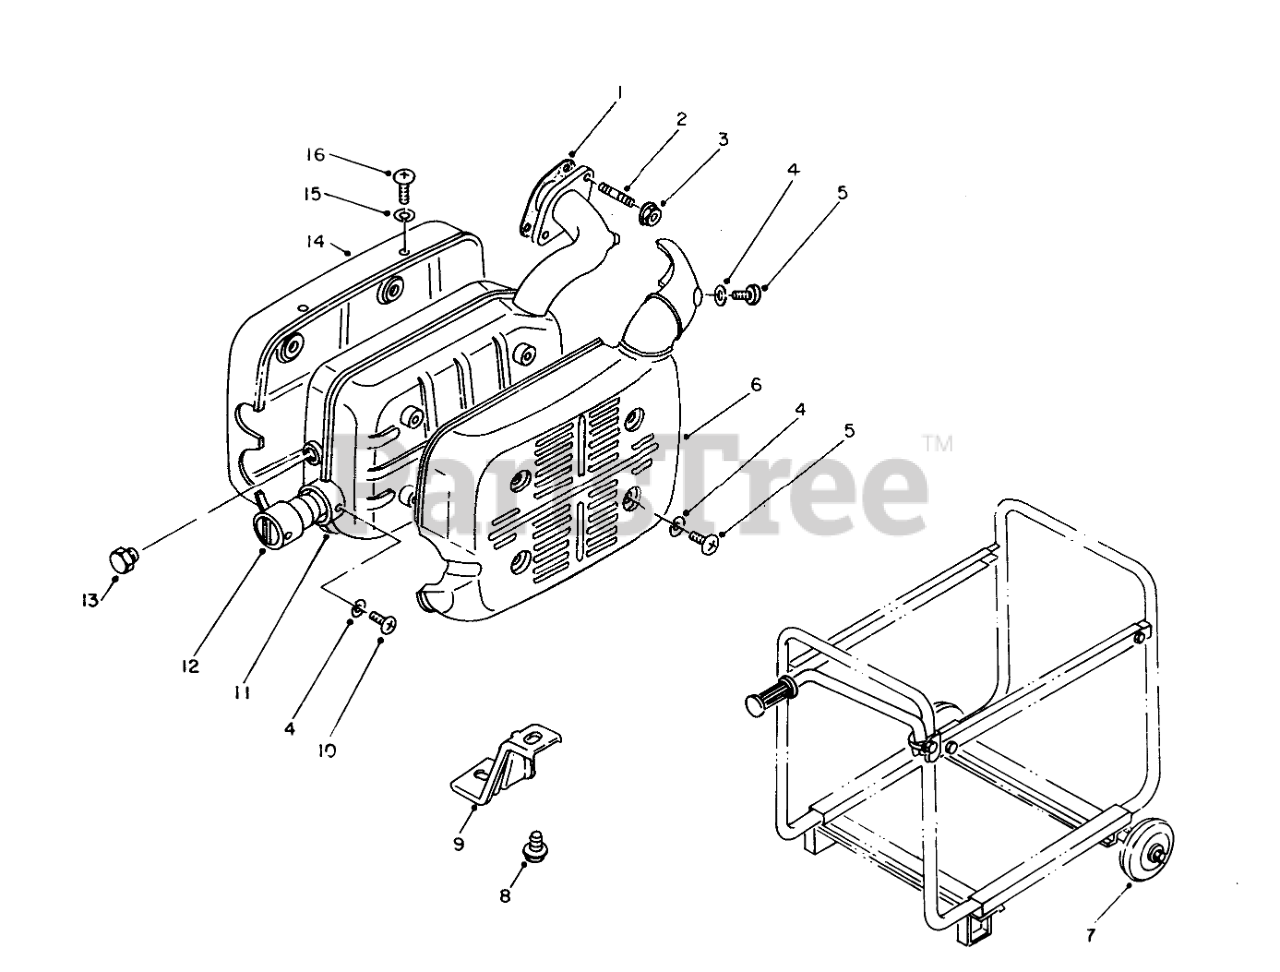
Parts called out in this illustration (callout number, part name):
4	LOCKWASHER
5	SCREW
11	MUFFLER ASM
